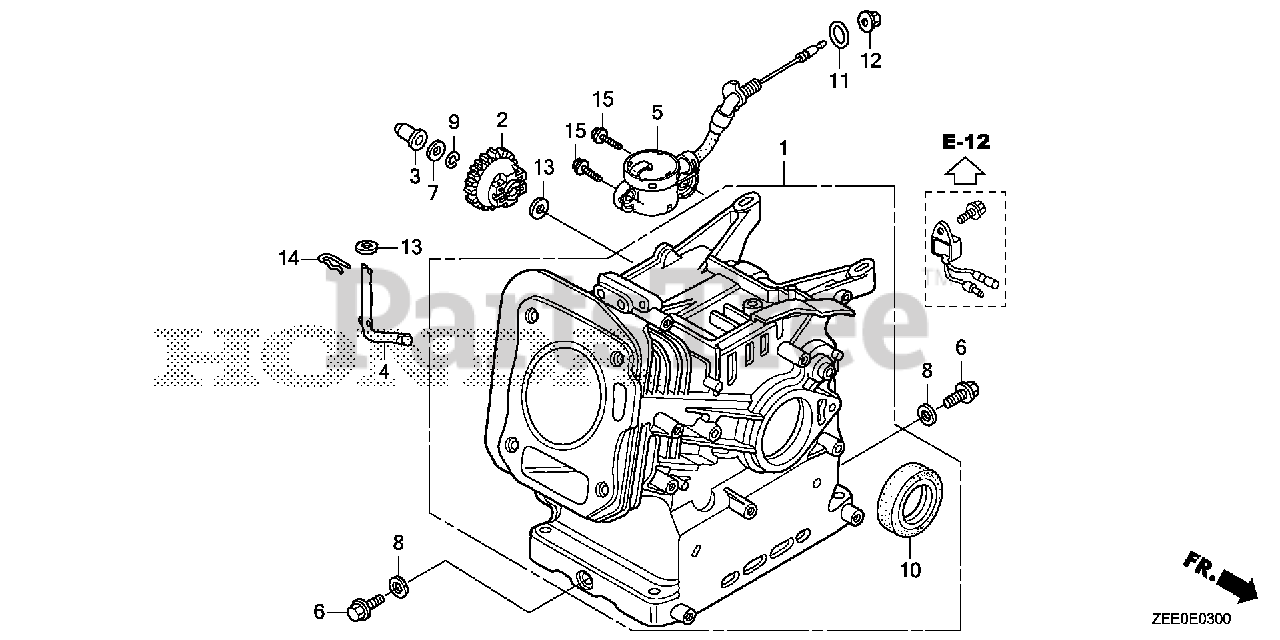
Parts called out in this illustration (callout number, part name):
1	CYLINDER ASSY.
2	GOVERNOR ASSY.
3	SLIDER, GOVERNOR
4	SHAFT, GOVERNOR ARM
6	BOLT, DRAIN PLUG
7	WASHER, THRUST (6MM)
8	WASHER, DRAIN PLUG (10.2MM)
9	CLIP, GOVERNOR HOLDER
10	OIL SEAL (25X41X6)
10	OIL SEAL (25X41X6) (ARAI) (NOT AVAILABLE)
13	WASHER, PLAIN (6MM)
14	PIN, LOCK (8MM)
